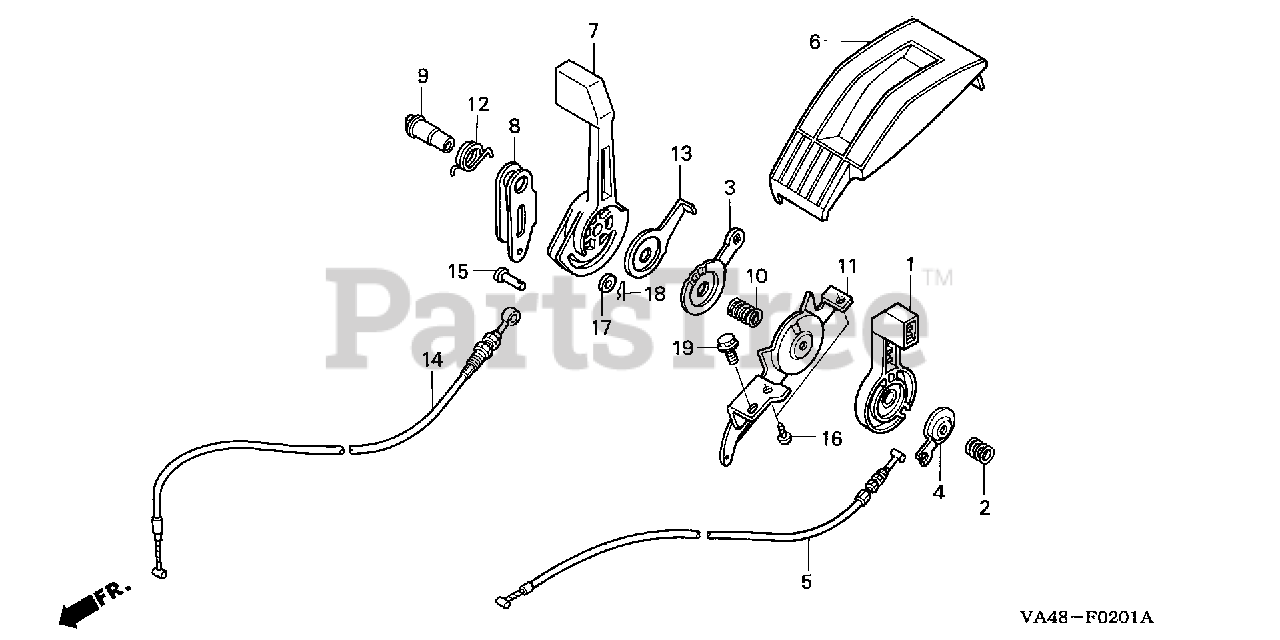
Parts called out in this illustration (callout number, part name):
1	LEVER, THROTTLE
2	SPRING, THROTTLE LEVER
3	SEAT, SPRING
4	SEAT, SPRING
5	CABLE, THROTTLE
6	COVER, CONTROL
7	LEVER, CHANGE
8	ARM, CHANGE LEVER
9	NUT, CHANGE LEVER
10	SPRING, CHANGE LEVER
11	PLATE, STOPPER
12	SPRING, ARM RETURN
13	PLATE, THRUST
14	CABLE, CHANGE
15	PIN (6X22)
16	SCREW, TAPPING (5X12)
17	WASHER, PLAIN (6MM)
18	PIN, LOCK (6MM)
19	BOLT, FLANGE (6X10)
